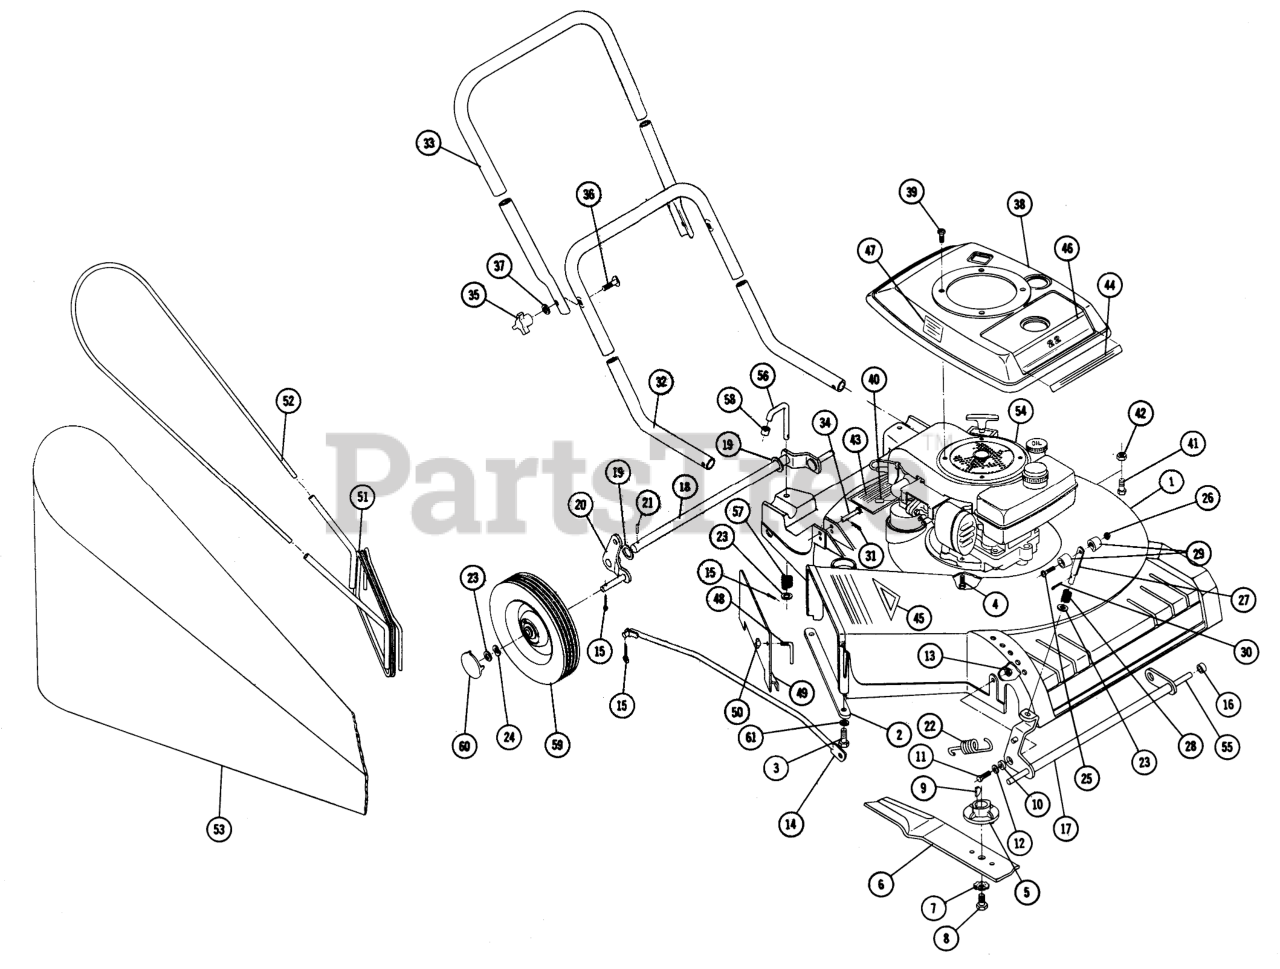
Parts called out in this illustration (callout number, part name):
1	Deck
2	Toe Guard
3	Bolt 5/16-18 x 3/4 Self Tap
4	Screw Hex 5/16-18 x 1 Sems
5	Drive Blade
6	22" BLADE
7	WASHER
8	Bolt 3/8-24 x 1 1/4 Nylok
9	Key Hi-Pro
10	Spacer
11	Bolt 5/16-18 x 1
12	Washer
13	Nut-Nylok
14	Rod-Wheel
15	Hairpin
16	Spacer
17	Height Adjustment Belcrank
18	Axle-Rear
19	Washer, 5/8
20	Belcrank Rear
21	ROLLPIN 3/16 X 7/8
22	SPRING
23	Washer
24	Washer
25	Bolt #10-24 x 3/4 Pan Head
26	#10-24 Kep-Nut
27	Plunger
28	Spring
29	Knob
30	Cotter Pin 1/8 x 3/4
31	Hairpin
32	Handle-Lower
33	Handle-Upper
34	Pin-Clevis
35	Knob
36	Bolt 5/16-18 x 1 3/4 Curved Head
37	Lockwasher 5/16 Int. Tooth
38	Shroud-Engine
39	Screw 1/4-28 x 1/2 Pan Head
40	Cap
41	Bolt 1/4-20 x 1/2
42	Nut, 1/4-20
43	NUT, CONDUIT, 1/2 INCH
44	Decal-Wheel Horse
45	Decal-ASA Triangle
46	Decal-22"
47	Decal-Throttle Control
48	Stud-Leaf Mulcher
49	Plate
50	Nut Wing 1/4-20
51	Frame
52	Hoop
53	Bag
54	Engine
55	Axle-Front
56	Hook
57	SPRING
58	Cap
59	Wheel & Tire Assembly
60	Cap-Hub
61	Lockwasher, 5/16
